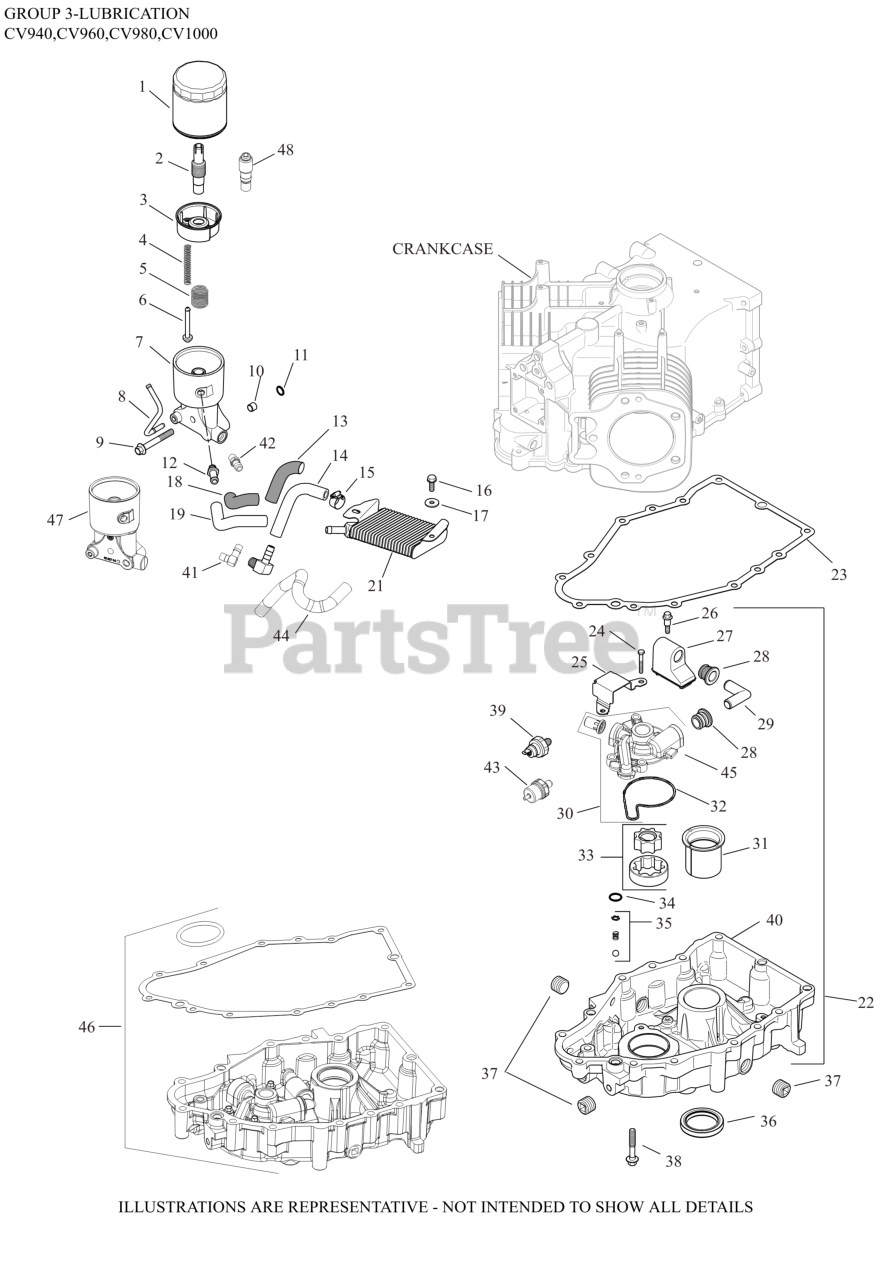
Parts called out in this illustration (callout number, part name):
1	OIL FILTER
2	NIPPLE, OIL FILTER ASSEMBLY-(#6213606S)
3	CUP, OIL FILTER ASSEMBLY
4	SPRING, OIL FILTER VALVE
5	SPRING, OIL FILTER CUP
6	VALVE, OIL FILTER
7	HOUSING, VERTICAL OIL FILTER
8	FITTING, PULSE PUMP
9	SCREW, FLG M8X1.25X60
11	O-RING, OIL PICK-UP
12	FITTING, HOSE TO PIPE
13	SLEEVE, ANTI ABRASION-USE 25 431 12-S
14	HOSE, OIL SUPPLY
16	SCREW, TAP M6X1.7X18
17	WASHER, FLAT 1/4"
18	SLEEVE, ANTI ABRASION-USE 25 431 12-S
19	HOSE, OIL RETURN
20	FITTING, 90 DEG. BARBED
21	COOLER, OIL ASSEMBLY
22	OIL PAN ASSEMBLY
23	GASKET, OIL PAN
26	SCREW, SHD THD FRM M6X.0X6.5
27	HOUSING, OIL PICK-UP ASSEMBLY
28	SEAL, PICK-UP TUBE
29	TUBE, OIL PICK-UP
32	O-RING, OIL PUMP HOUSING
33	PUMP ASSEMBLY, OIL/GEROTOR
35	KIT, CHECK BALL
36	SEAL, OIL-(#2503218S)
36	SEAL, OIL-(#2503217S)
37	PLUG, PIPE 1/2 NPTF SQ CTSK
38	SCREW, HEX FLANGE
39	SWITCH, OIL PRESSURE
45	HOUSING, OIL PUMP MACH-USE 62 081 38-S
